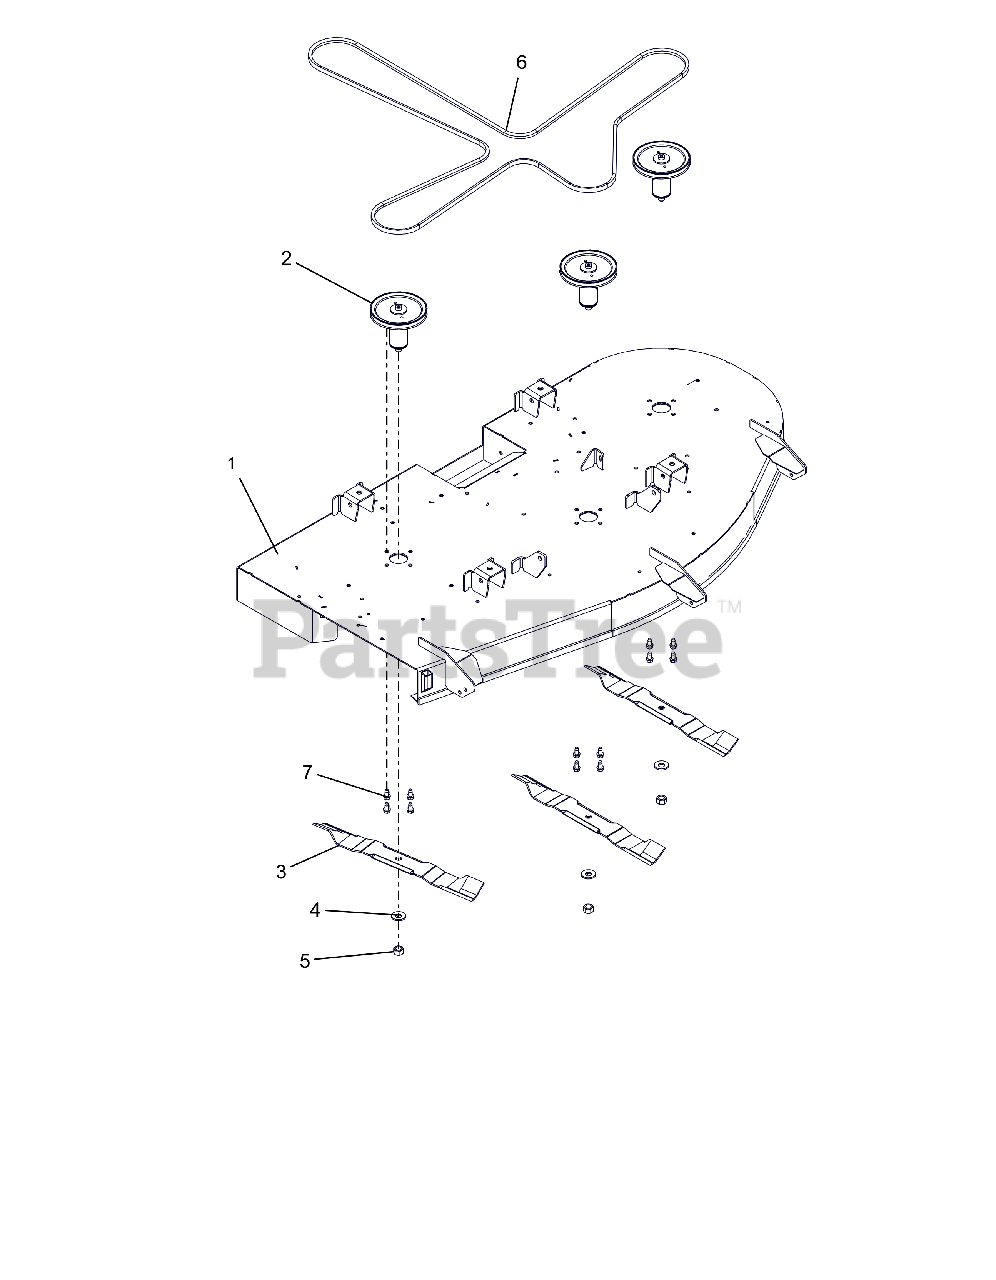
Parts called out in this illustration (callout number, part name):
1	KIT, ARIENS DECK 60" WITH DECALS
2	KIT, DECK SPINDLE ASM-60
3	BLADE, 21" 35 DEG
4	WSHR-BLVL .669X1.535X.138
5	NUT-STD .625-18 ZCC
6	BELT, HA
7	SCR,TAP .375-16X.75 HWH TR ZCC
